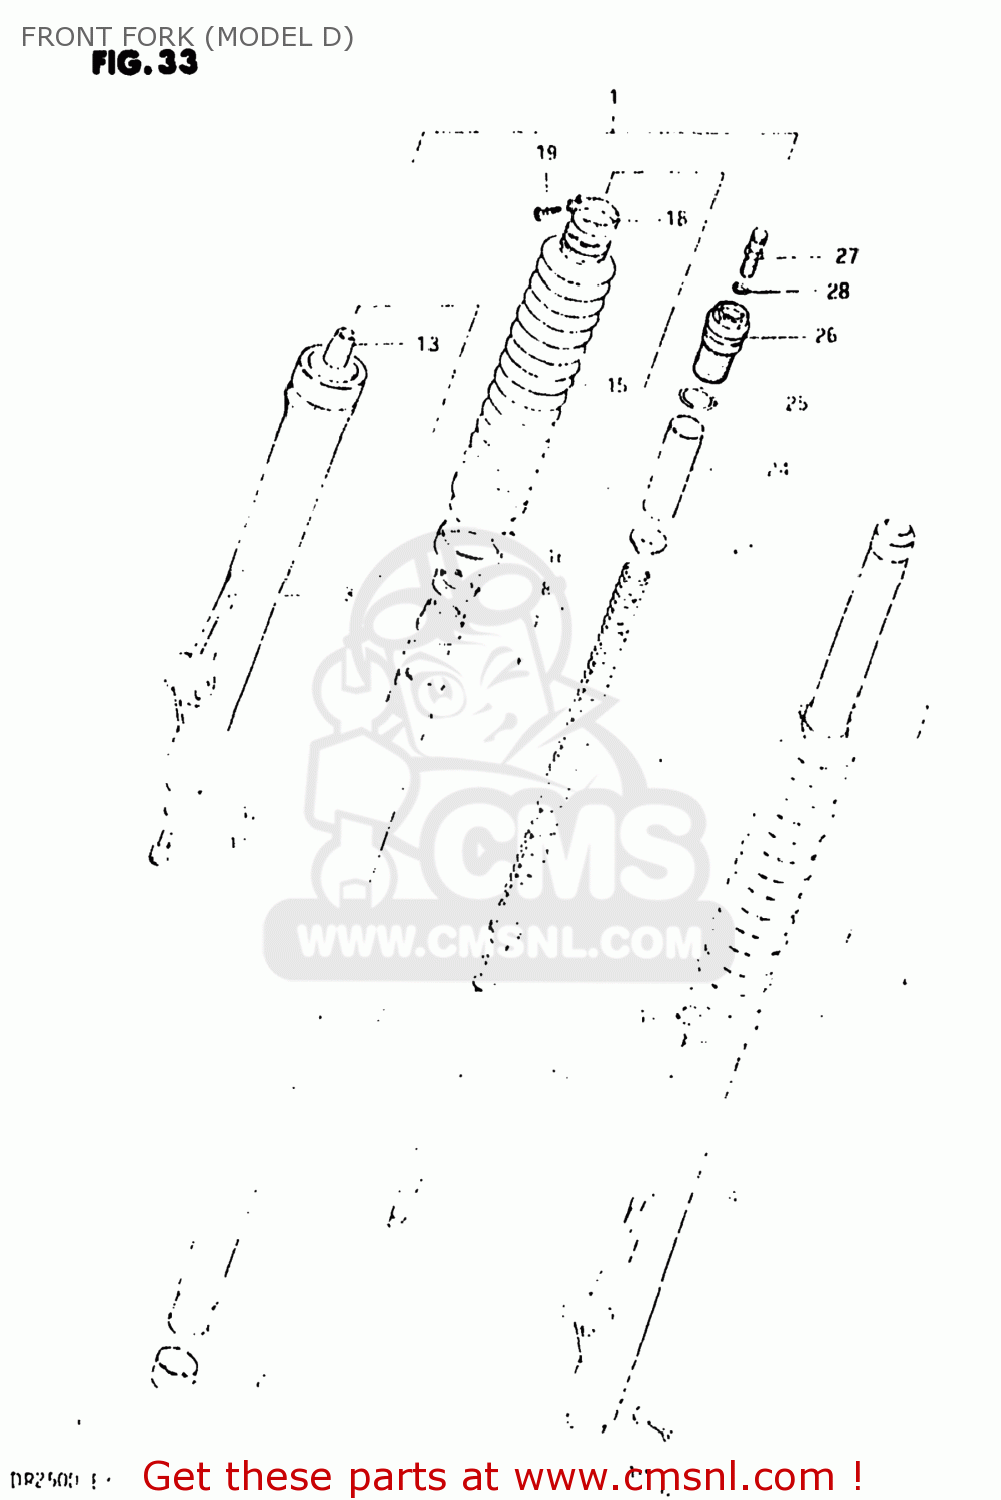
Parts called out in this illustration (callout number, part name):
1	DAMPER ASSEMBLY,RIGHT
2	DAMPER ASSEMBLY,LEFT
3	TUBE,OUTER,RIGHT
4	TUBE,OUTER,LEFT
5	OIL SEAL,FRONT FORK
6	7
7	SEAL,DUST
8	CASE,DUST SEAL
9	SCREW
10	GASKET,DRAIN,PLUG (NAS)
11	BOLT,FORK CYLINDER(10X25)
12	GASKET (NAS)
13	PIECE,OIL LOCK
14	CYLINDER,FRONT FORK
15	BOOT
16	BAND,FRONT FORK COVER
17	BAND,FRONT FORK COVER
18	BAND,BOOT
19	SCREW
20	TUBE,FORK,INNER
21	PISTON
22	SPRING,FRONT FORK
23	GUIDE,FRONT FORK SPRING C
24	COLLAR,SPRING
25	O RING
26	BOLT,FORK
27	VALVE,FRONT FORK AIR
28	O-RING
